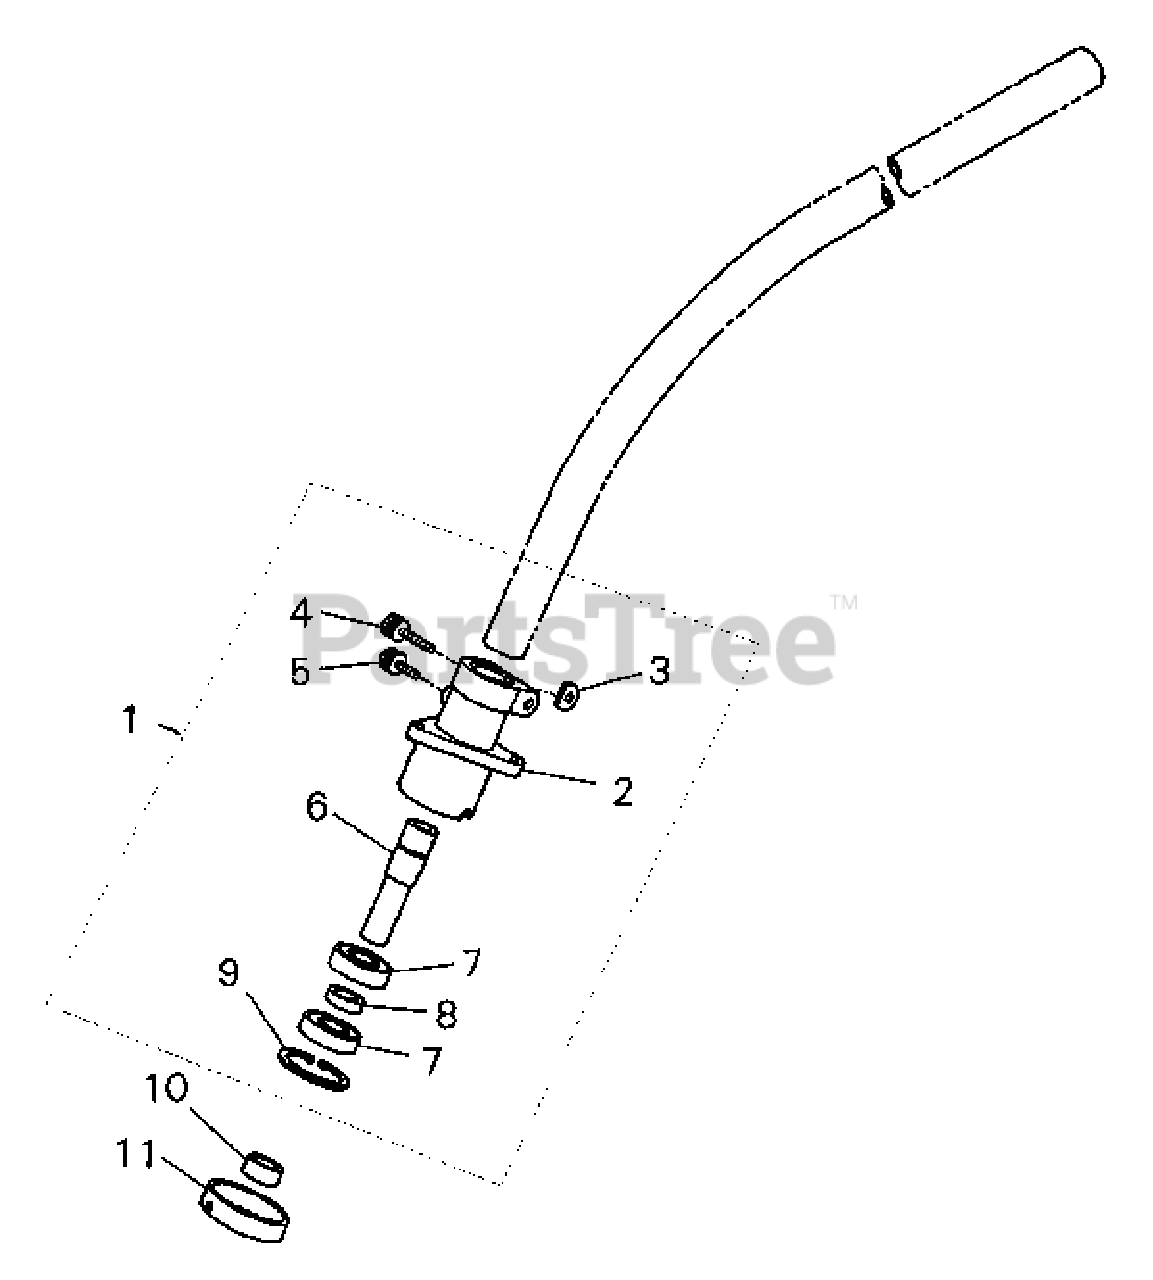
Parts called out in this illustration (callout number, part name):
1	GEAR CASE ASSY
2	HOUSING, GEAR CASE
3	D-WASHER
4	BOLT M5×25
5	BOLT
6	SHAFT
7	BEARING, BALL 6001 DDU
8	COLLAR (A)
9	RING, SNAP Ø28
10	COLLAR (B)
11	HOLDER
